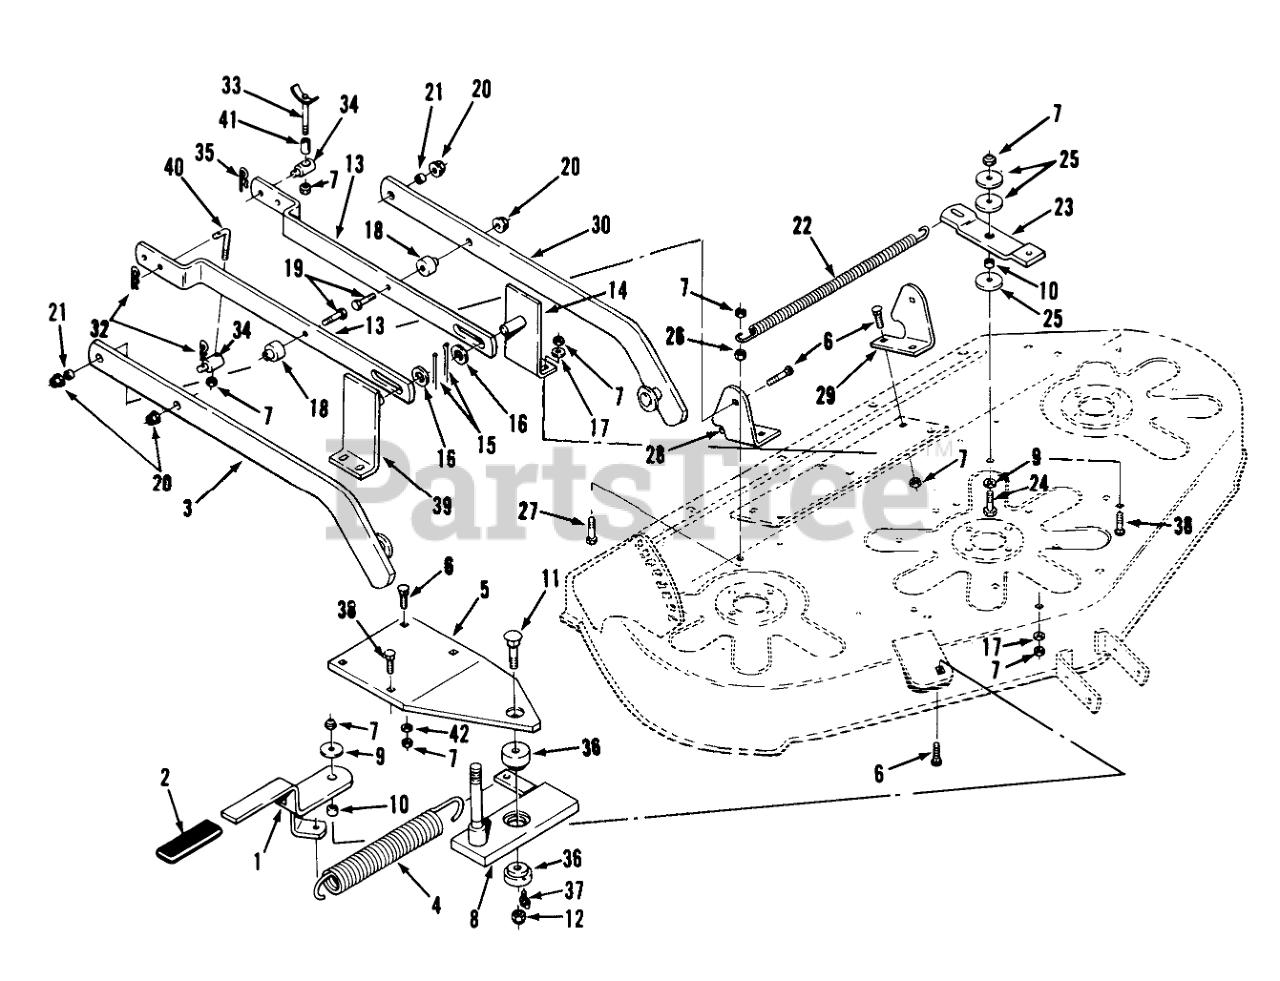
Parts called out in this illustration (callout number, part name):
1	Lever
3	Draft Bar RH
4	Spring
5	Plate
6	BOLT-CARR
7	NUT-LOCK, NI
8	Countershaft
9	WASHER
10	SPACER
11	SCREW-CARR
12	NUT-LOCK, NI
13	Bar-Leveler
14	Bracket
15	PIN-COTTER
16	WASHER-FLAT
17	WASHER-FLAT
18	SPACER
19	SCREW-HH
20	LOCKNUT-FLANGE
21	SPACER
22	SPRING - EXTENSION
23	Arm-Idler
24	SCREW-HH
25	WASHER
26	NUT-HEX
27	SCREW-HH
28	Bracket RH
29	Bracket LH
30	Draft Bar LH
32	PIN-COTTER
33	WLDMT-HANGER ROD
34	Trunion
35	PIN-COTTER
36	BUSHING
37	Fitting-Grease
38	BOLT-CARR
39	Bracket RH
40	ROD-LIFT
41	Spacer
42	WASHER
